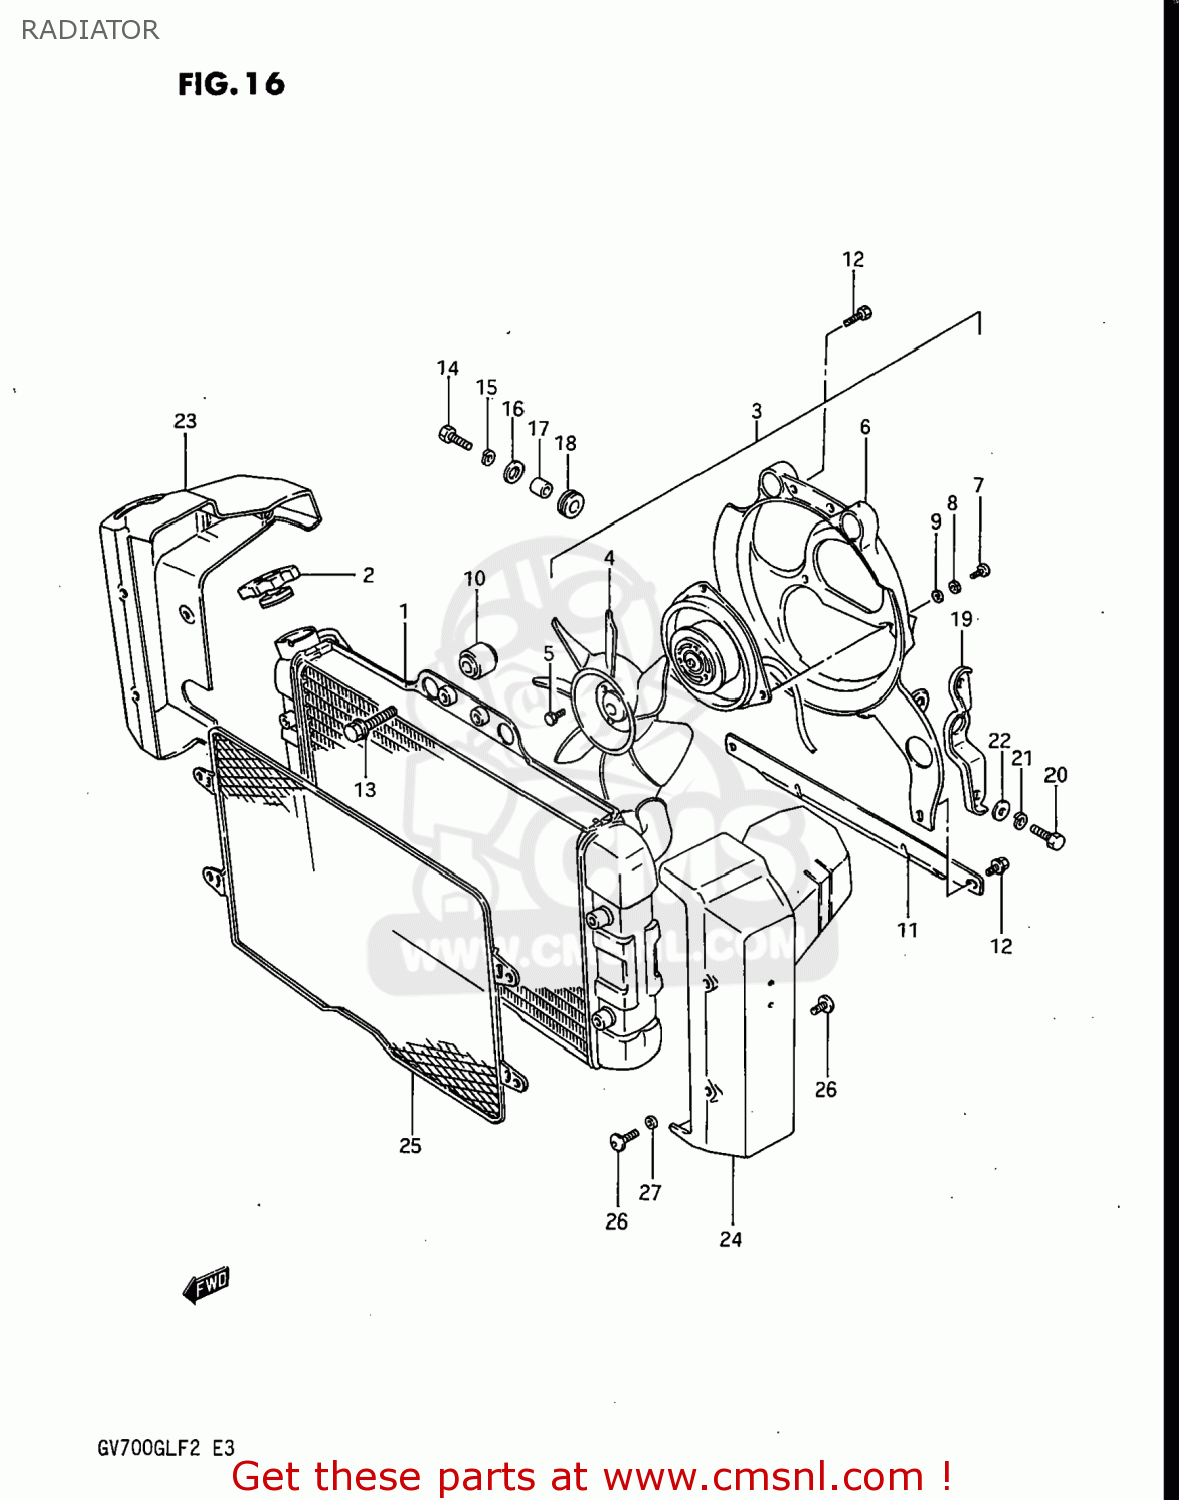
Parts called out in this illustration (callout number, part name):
1	RADIATOR ASSEMBLY,WATER
2	CAP,RADIATOR
3	FAN ASSEMBLY,RADIATOR (ASB)
4	FAN
5	BOLT
6	SHROUD,FAN
7	SCREW 5X10
8	LOCK WASHER
9	WASHER
10	CUSHION,RADIATOR NO.1
11	PLATE,MUD GUARD
12	BOLT,RADIATOR FAN
13	BOLT
14	BOLT 6X16
15	LOCK WASHER
16	WASHER (6.5X18X1.6)
17	SPACER (7X9X7)
18	CUSHION
19	BRACKET,RADIATOR
20	BOLT 6X16
21	WASHER,LOCK
22	WASHER
23	COVER,RADIATOR,RIGHT
24	COVER,RADIATOR,LEFT
25	NET,RADIATOR
26	SCREW
27	SPACER (7X9X4)
